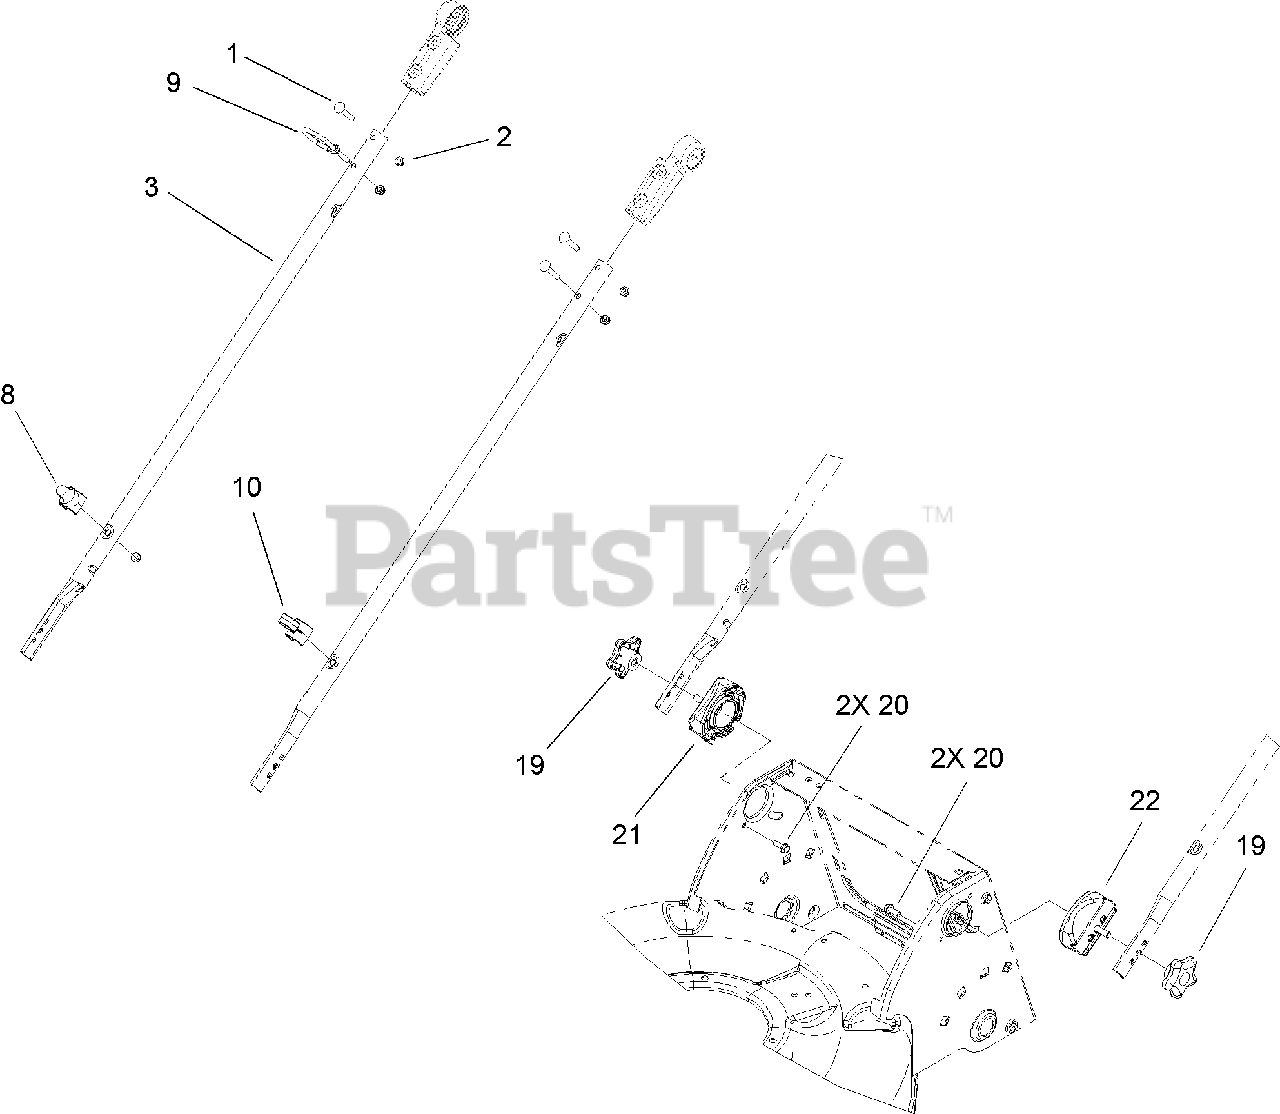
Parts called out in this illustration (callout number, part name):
1	SCREW-CARR
2	NUT-LOCK, NI
8	GUIDE-ROPE, LOWER
9	GUIDE-ROPE, UPPER
10	Guide-Cable
19	KNOB-HANDLE
20	SCREW-HWH
21	RH HANDLE MOUNT ASM
22	LH HANDLE MOUNT ASM
23	STRAP-TIE
